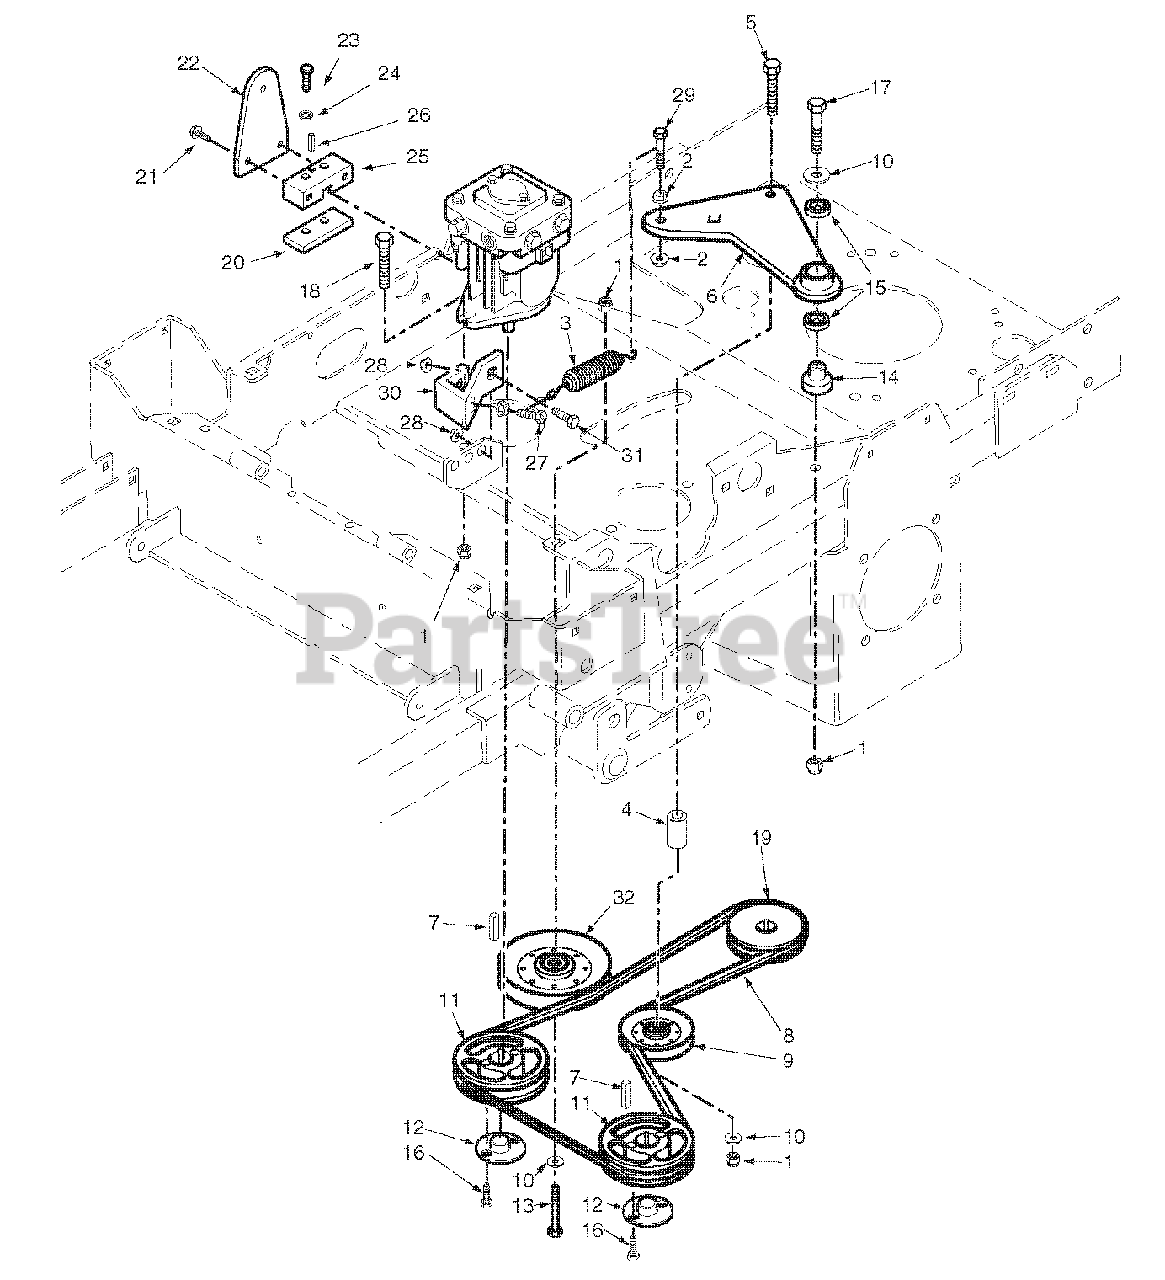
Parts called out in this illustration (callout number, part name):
1	Nut, Elastic Stop 3/8-16
2	Nut, Serrated Flange 3/8-16
3	Spring, Pump Idler
4	Spacer
5	Bolt, Hex Head 3/8-16 x 2-3/4"
6	Idler Arm Assy., Pump Drive
7	Key, 5 x 5 x 25mm
8	Belt, Transmission
9	Pulley, 3-1/2" Dia. Idler
10	Flatwasher, 3/8-.391 x .938 x .105"
11	Pulley, 5.75" OD Taper Bore
12	Hub, Tapered, 15mm Bore
13	Bolt, 3/8-16 x 2"
14	Pivot, Idler
15	Bearing
16	Bolt, Hex Head 1/4-20 x 1"
17	Bolt, Hex Head 3/8-16 x 2-1/2"
18	Bolt, Hex Head 3/8-16 x 1-1/2"
19	Pulley, 5.75" Dia. - 1.125" Bore
20	Clamp Plate
21	Hex Head Capscrew, 1/4-20 x 3/4"
22	Control Lever, Pump
23	Hex Head Capscrew, 1/4-20 x 3/4"
24	Lockwasher, 1/4"
25	Block, Pump Control
26	Roll Pin
27	Bolt, Hex Head 3/8-16 x 1-1/2"
28	Nut, Serr. Flange 3/8-16
29	Bolt, Hex Head 3/8-16 x 1-1/2"
30	Bracket
31	Bolt, Hex Head 3/8-16 x 1"
32	Pulley, 5" Dia. Idler
